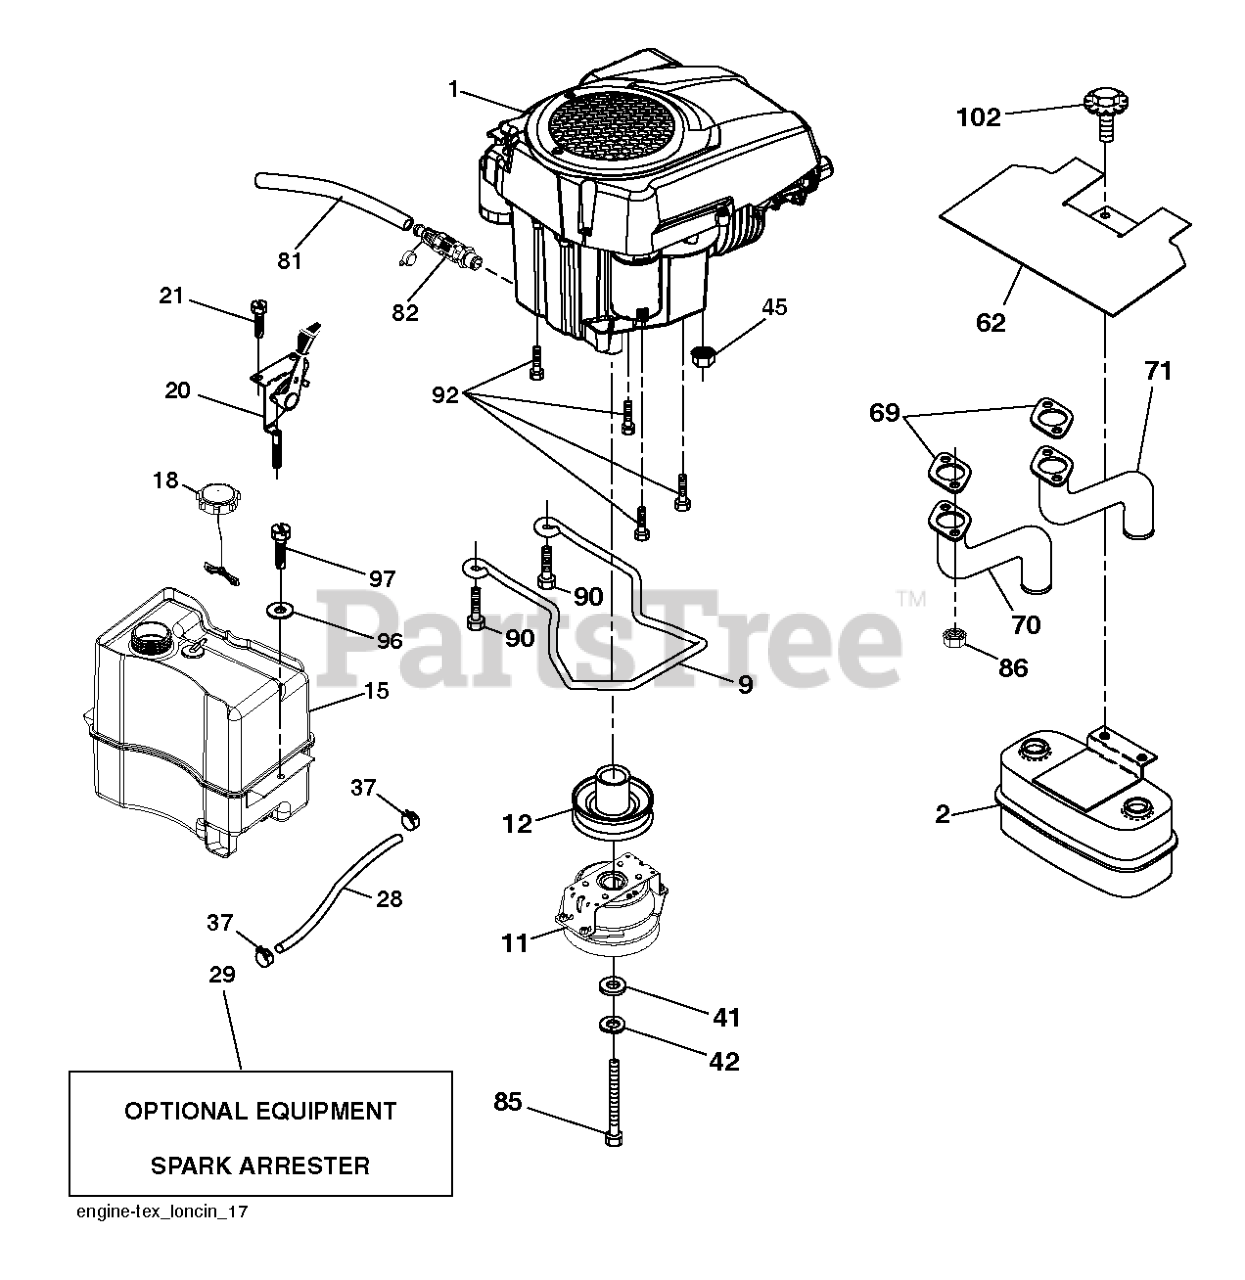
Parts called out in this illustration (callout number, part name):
2	MUFFLER.ASM.TWIN.MNTG.BRACKET
11	CLUTCH MAGNETIC CLUTCH & BRAKE
12	PULLEY.ENGINE.TUFFTORQ
15	TANK.ASSEMBL.2.5GAL.NON-EPA
18	CAP ASM.FUEL.2.25"FR.
20	CONTROL.TH/CK.COBRA.B&S.TWN.BK
28	LINE.FUEL.20
29	KIT.SPARK ARRESTOR 794945 B&S
37	HOSE CLAMP
45	NUT HEXAGON WITH FLANGE, SERRA
62	SHIELD.HEAT.MUFFLER
81	TUBE, DRAIN OIL ASM.
82	VALUE.OIL.DRAIN
85	BOLT.HEX.7/16-20X3.75.GR5.RED
86	NUT.HEX.FLANGE.TOPLOCK
90	SCREW 3/8-16X1
92	SCREW 3/8-16X1
97	SCREW HEXWSHR 1/4-20X3/4
102	SCREW
